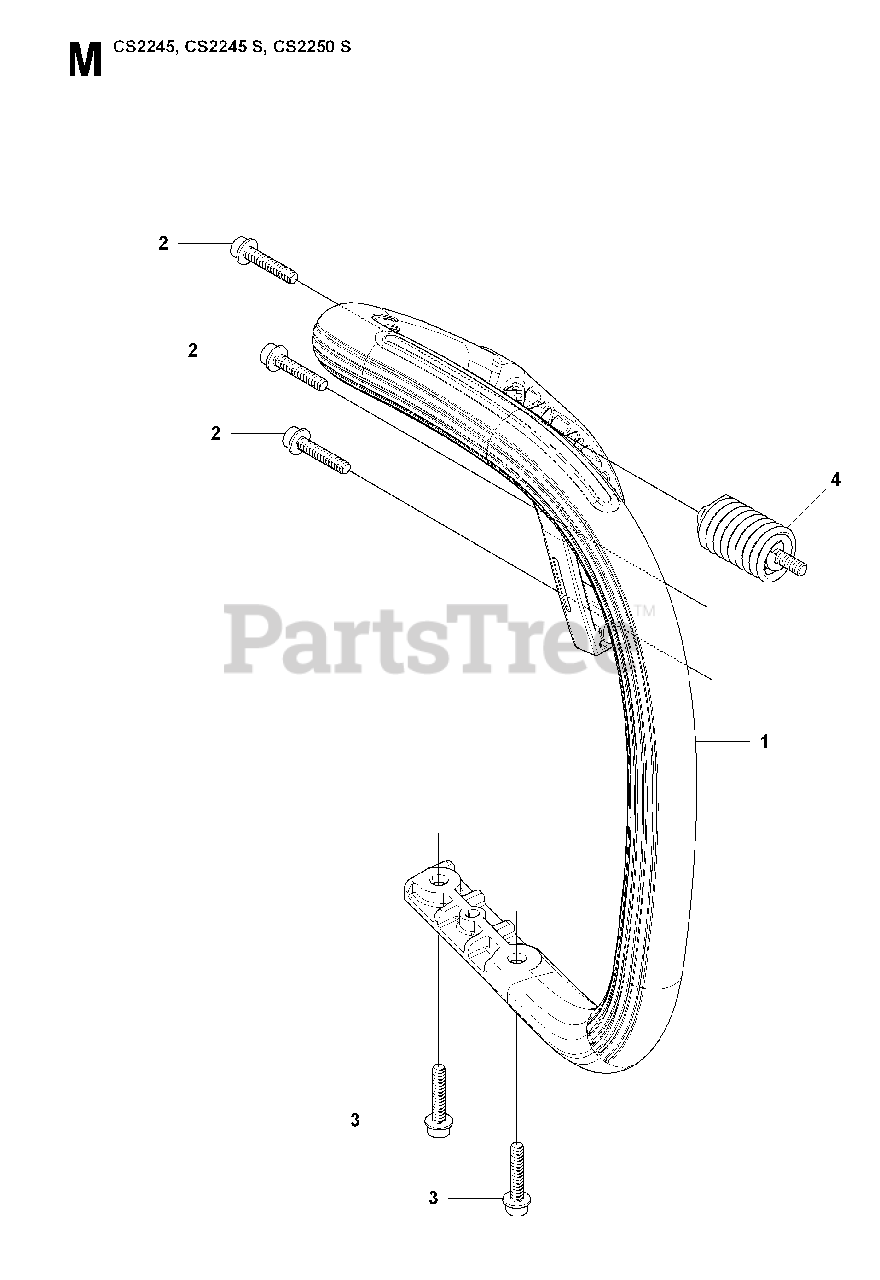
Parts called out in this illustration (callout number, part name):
1	FRONT HANDLE
2	SCREW IHSCFT
4	INSULATOR
